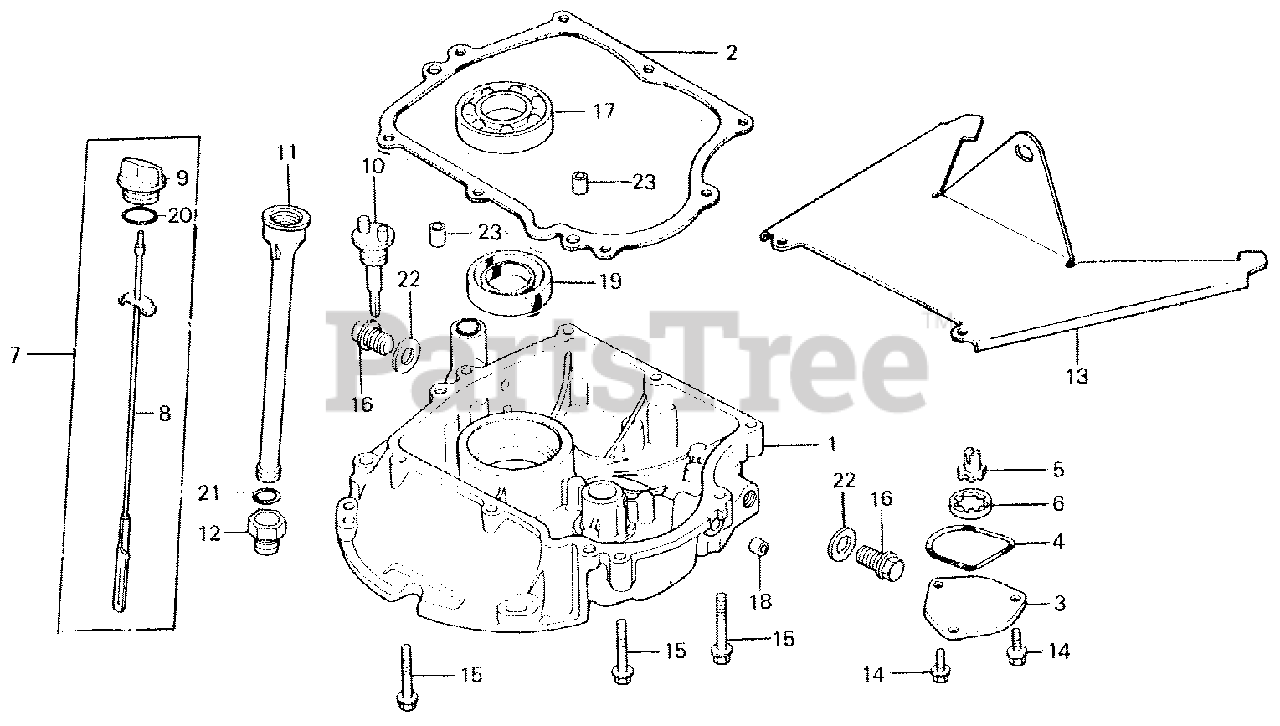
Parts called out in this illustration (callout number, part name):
1	PAN, OIL
2	GASKET, OIL PAN
3	COVER, OIL PUMP
4	O-RING, COVER
5	ROTOR (INNER)
6	ROTOR, OIL PUMP (OUTER)
7	GAUGE ASSY., OIL LEVEL
8	DIPSTICK, OIL
9	CAP, OIL
10	CAP, OIL FILLER
11	PIPE, OIL FILLER
12	BOLT, JOINT
14	BOLT, FLANGE (6X12) (CT200)
15	BOLT, FLANGE (6X32)
16	BOLT, DRAIN PLUG
17	BEARING, RADIAL BALL
18	OIL SEAL (6X11X4)
19	OIL SEAL (25.4X40X7)
20	O-RING (26X2.7)
21	O-RING (15X2.5)
22	WASHER, DRAIN PLUG (12MM)
23	PIN A, DOWEL (8X14)
